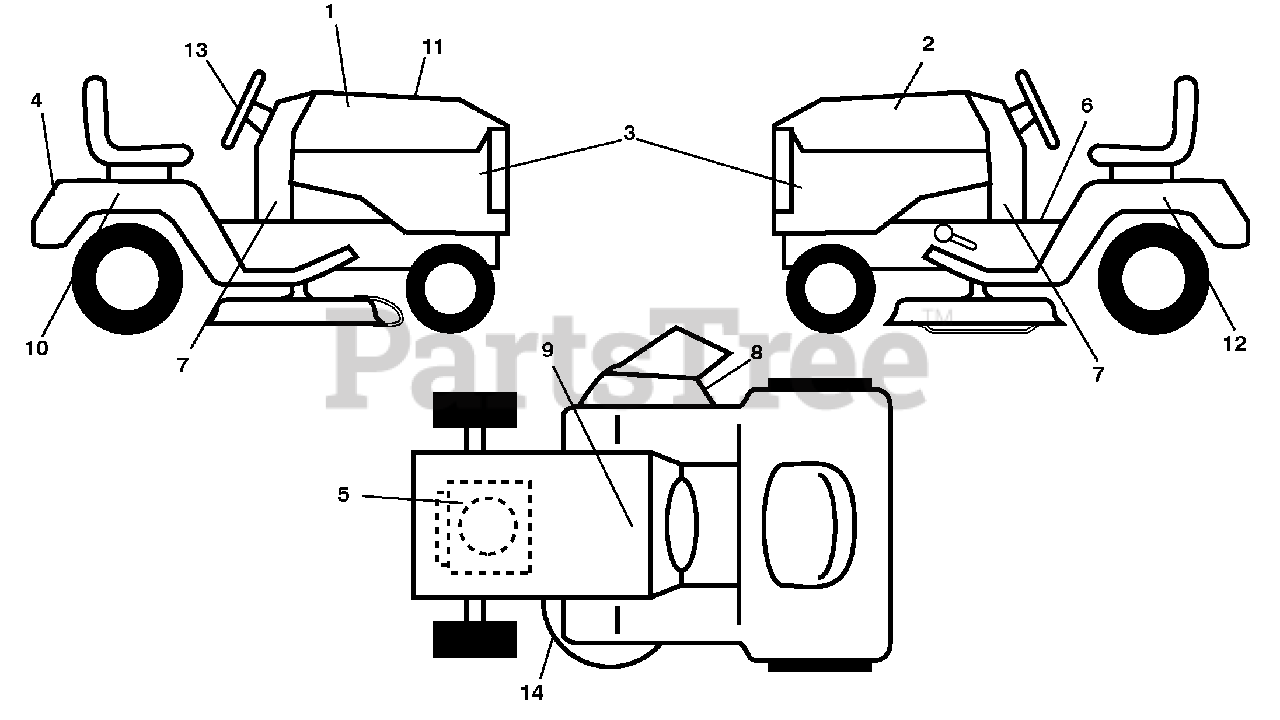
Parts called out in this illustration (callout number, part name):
1	Decal, Hood RH
2	Decal, Hood LH
3	Decal, Side Panel
4	Decal, Fender
5	Decal, Eng H.P.
6	Decal, Fender Operator's
7	Decal, Lower Dash
8	Decal, Warning
9	Decal, Battery Dnge/Poi
10	Decal, Fender SD RH
11	Decal, Replacement
12	Decal, Fender SD LH
13	Decal, Steering Wheel
14	Decal, Mower Schematic
14	Pad, Footrest Control
14	Decal, Bypass
14	Pad, Footrest, LH
14	Manual, Operator's (Eng/French)
14	Manual, Parts (Eng/French)
